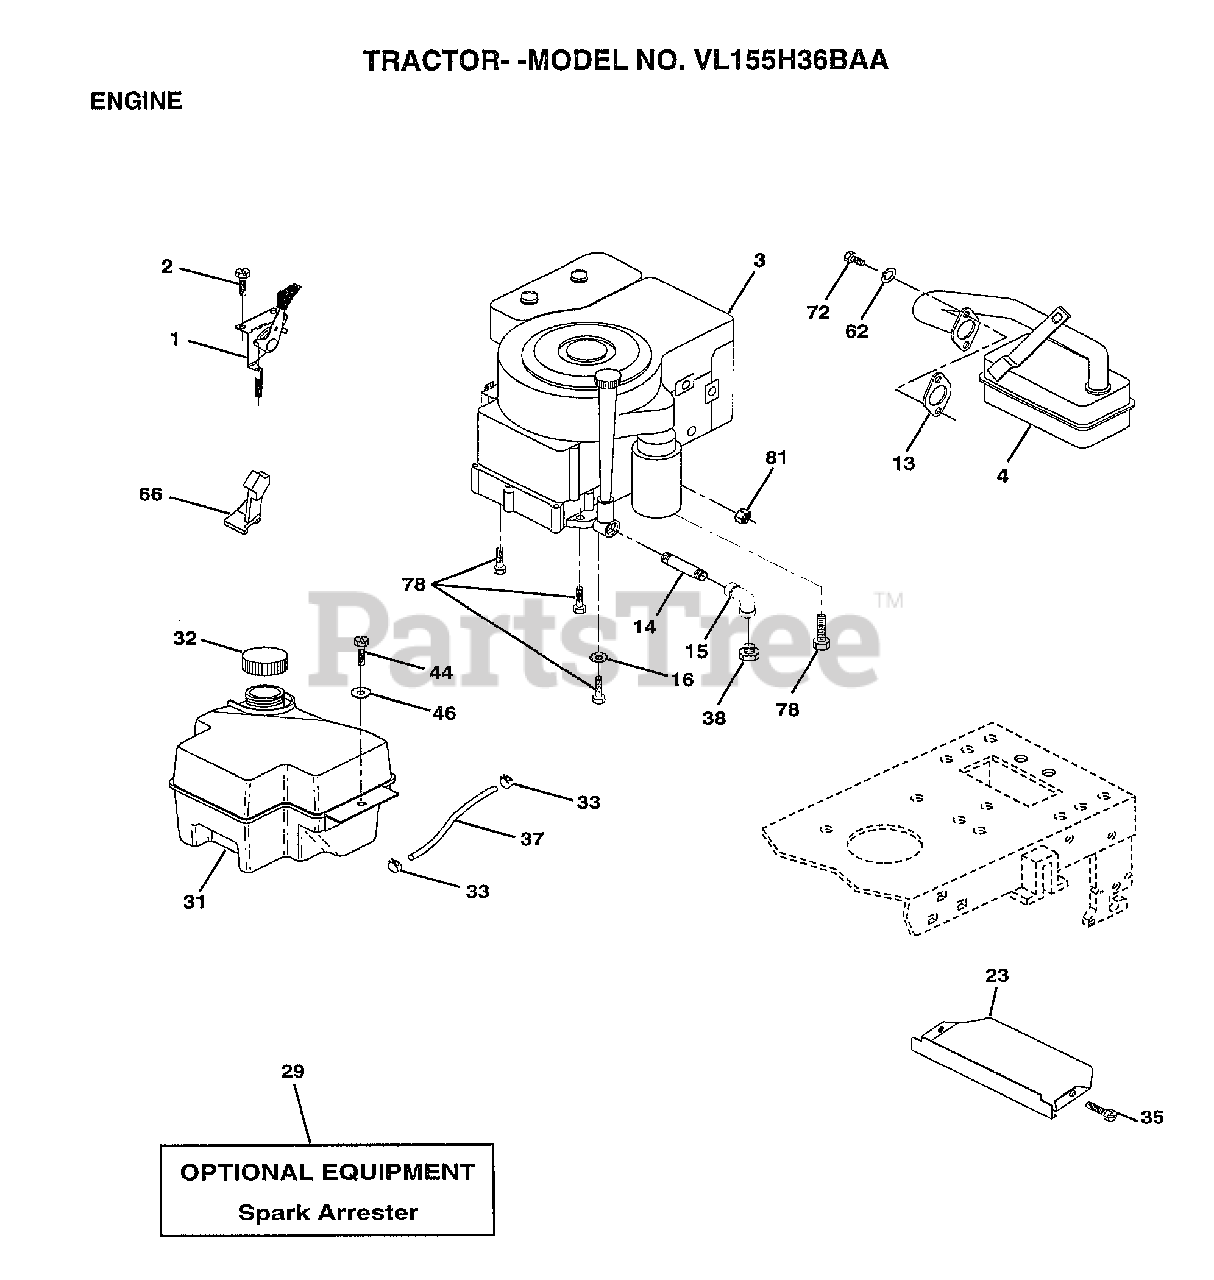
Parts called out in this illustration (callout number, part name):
1	CONTROL.THTL.23.5
2	SCREW LT
4	MUFFLER
14	PIPE NIPPLE
15	ELBOW
16	LOCKWASHER
23	SHIELD.BRN/DBR.GD
31	TANK.FUEL.FRONT.
32	CAP ASM FUEL
33	HOSE CLAMP
35	SCREW
37	LINE FUEL
44	SCREW HEX CRT
46	WASHER
62	LOCKWASHER
66	"STOP,DASH THROTT"
72	SCREW
78	SCREW
81	NUT
